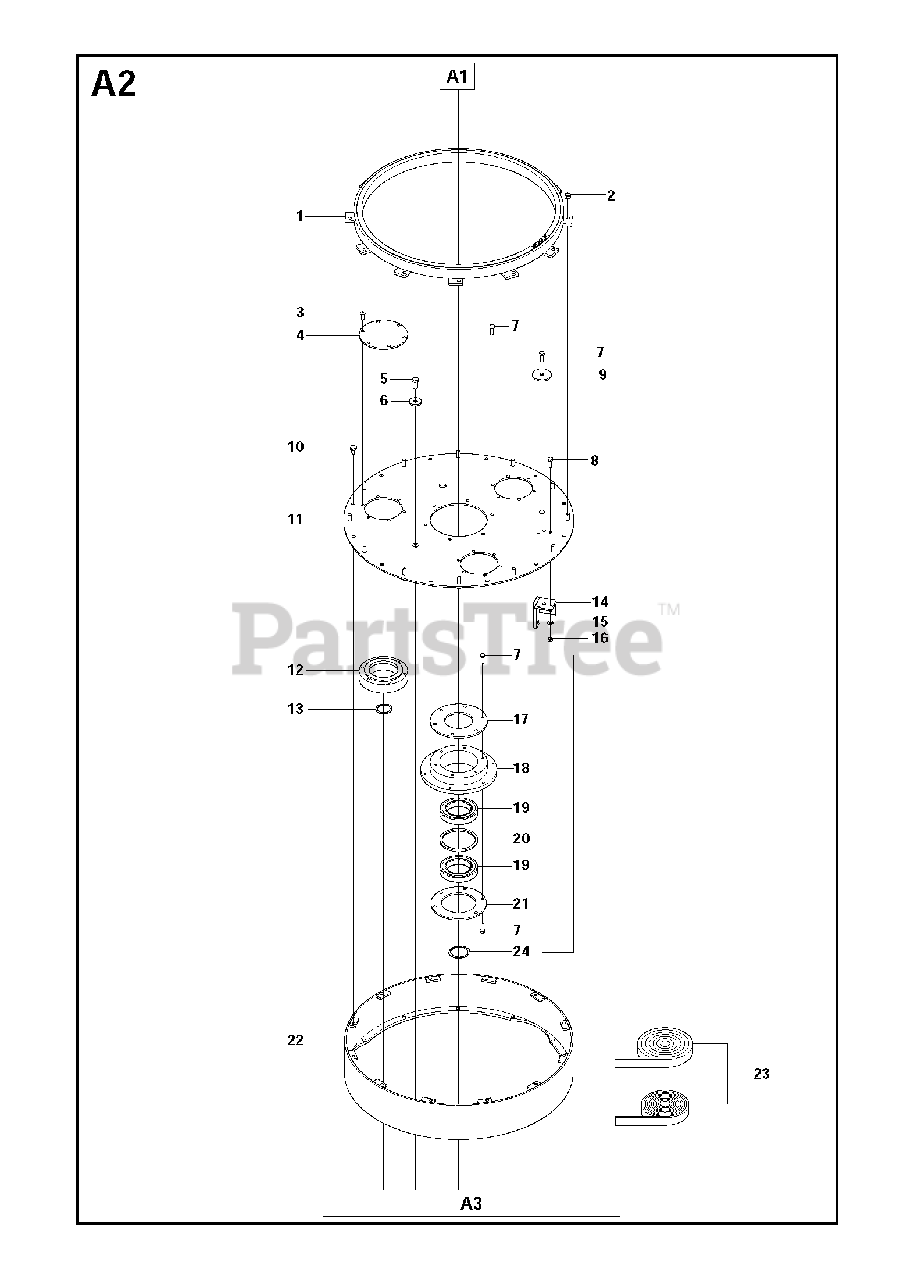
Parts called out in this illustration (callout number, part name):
2	HEXAGON LOCKING NUT
15	WASHER
16	HEXAGON LOCKING NUT
